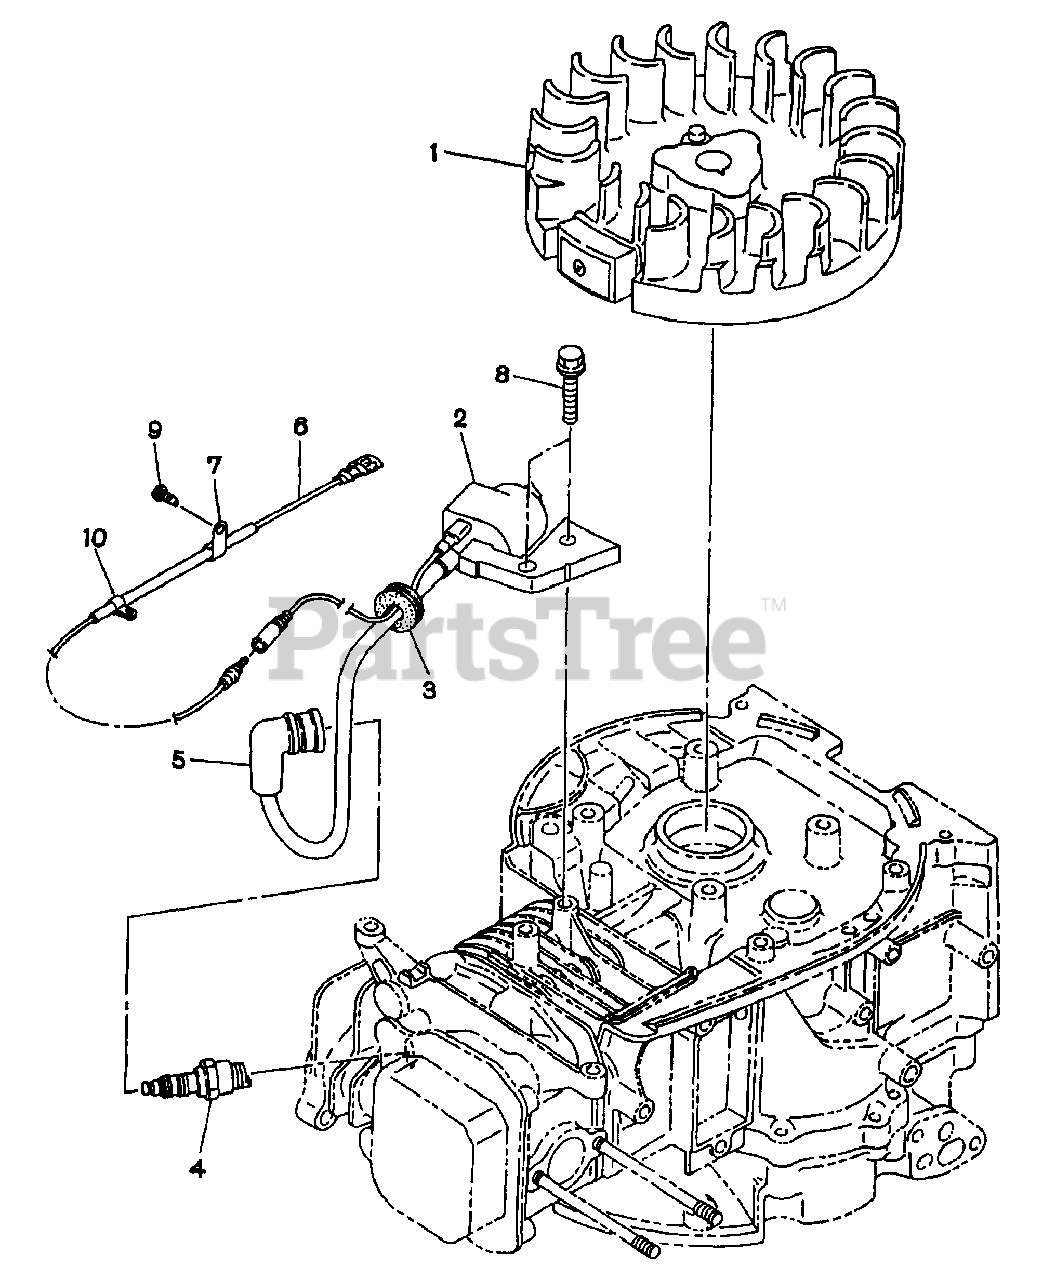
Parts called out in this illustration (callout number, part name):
1	FLYWHEEL, compl.
2	IGNITION COIL. compl.
4	SPARK PLUG
5	SPARK PLUG CAP
6	WIRE 1, compl.
8	FLANGE BOLT
9	TAPPING SCREW
10	CLAMP, compl.
